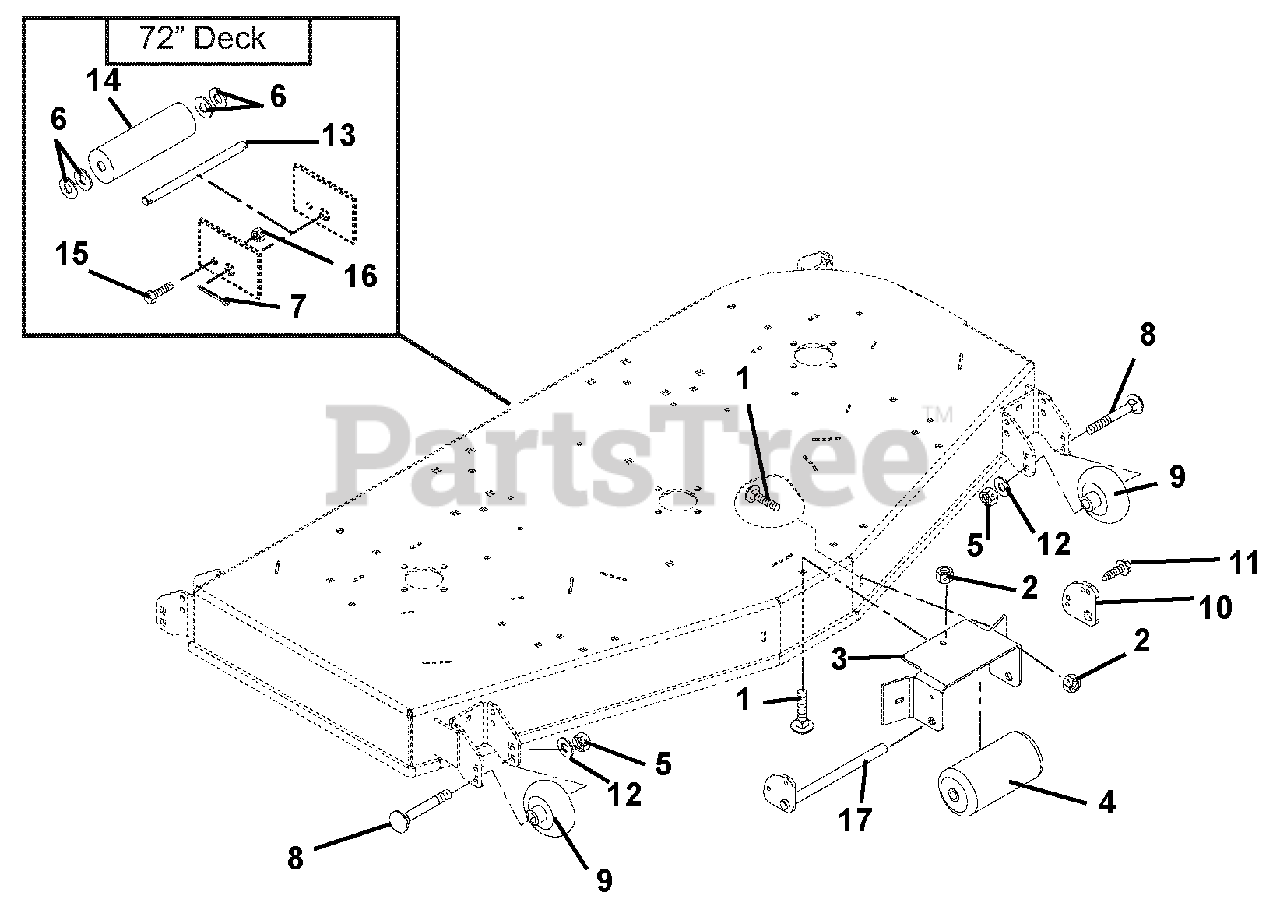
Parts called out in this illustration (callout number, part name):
1	Bolt-Round Head Square Neck .38-16 x 1.00 Grade 5
2	Nut-Locking-Top-Flange .38-16
3	Bracket- Anti-Scalp Roller
5	Nut-Locking-Nylon .50-13
6	Washer-Flat-Steel .656 x 1.31 x .095
7	Pin-Cotter .25 x 2.00
8	Bolt-Round Head Square Neck .50-13 x 5.00 Grade 2
9	Wheel, 3 x 5
10	Anti-Scalp Washer
11	Screw-Tapping .25-20 x .62 Hex Washer Head
12	Washer-Flat-Steel .531 x 1.06 x .095
13	Shaft, Center Roller (321)
14	Roller, Gage (321)
15	Bolt-Hex .25-20 x .75 Grade 5 (321)
16	Nut-Locking-Center .25-20 (321)
17	Weldment, Roller Bracket
